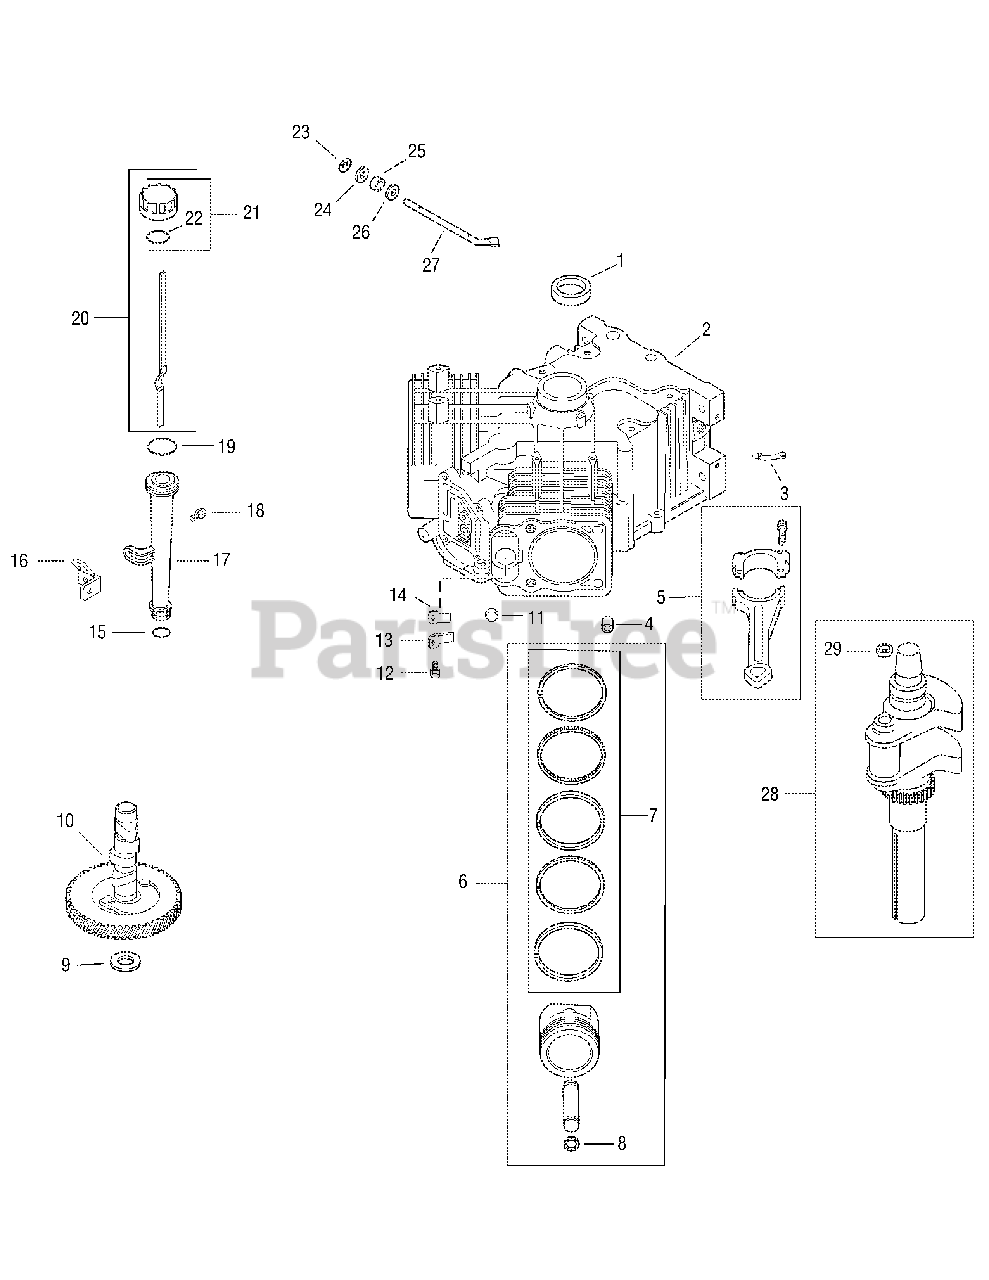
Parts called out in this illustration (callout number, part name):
1	Seal, front oil
4	Pin, locating
5	Connecting Rod (Std.)
5	Connecting Rod (.25)
6	Piston w/ Ring Set (Std.)
6	Piston w/ Ring Set (.08)
6	Piston w/ Ring Set (.25)
6	Piston w/ Ring Set (.50)
7	Ring set (Std. & .08)
8	Retainer, piston pin
9	Shim, camshaft - red as required
9	Shim, camshaft - black as required
9	Shim, camshaft - white as required
9	Shim, camshaft - blue as required
9	Shim, camshaft - yellow as required
9	Shim, camshaft - green as required
9	Shim, camshaft - gray as required
10	Camshaft
11	Plug, cup
12	Screw, hex. flange M5 x 0.8 x 10
13	Retainer, reed
14	Reed, breather
15	O-Ring, lower oil fill tube
16	Bracket, oil fill tube
17	Tube, oil fill
18	Screw, hex. flange M5 x 0.8 x 16
19	O-Ring, upper oil fill tube
20	Dipstick assembly
21	Kit, oil fill cap
22	O-Ring, dipstick
23	Retainer, ring
24	Washer, plain 9 mm
25	Seal, governor cross shaft
26	Washer, plain 1/4"
27	Shaft, governor cross
28	Crankshaft
29	Plug, cup
